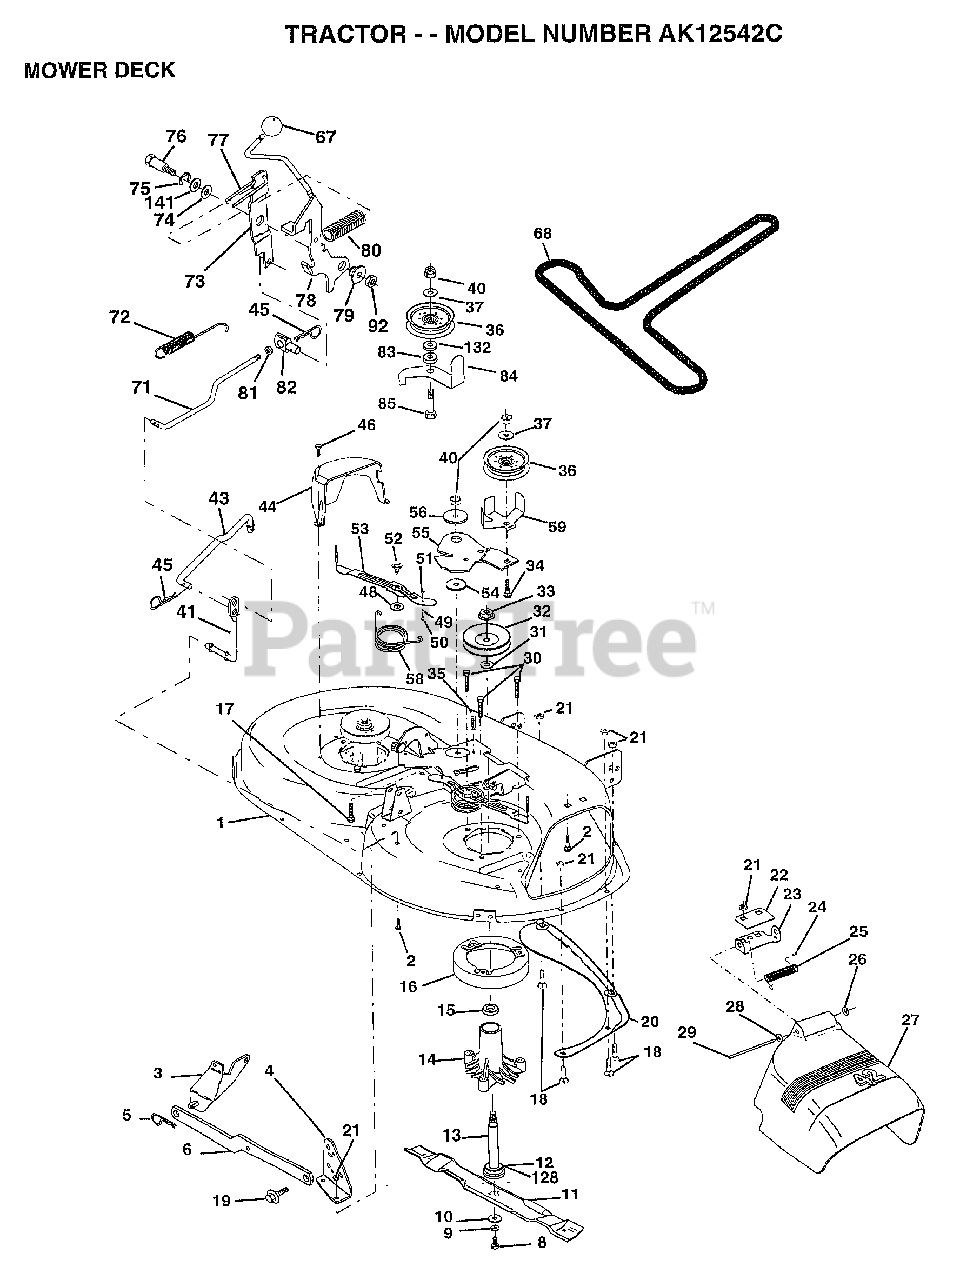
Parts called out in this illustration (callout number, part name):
1	"HOUSING ASSY.42"""
2	BOLT
3	BRKT ASM SWAY BAR
4	BRKT DECK SW BAR
8	BLADE BOLT
10	WASHER.HARD.BLADE
11	"BLADE.42"" HIPERF"
12	BEARING.BALL
14	HSG ASM MANDREL
15	BEARING
16	STRIPPER RND MWR
17	BOLT RDHD 3/8-16
18	BOLT
19	BOLT SHD 5/16-18
20	BAFFLE VORTEX 42
22	STIFFENER BRKT
23	DEFLECTOR BRKT
24	CAP-SLEEVE LT
25	SPRING TORSION
26	NUT PUSH M
27	DEFLECTOR.SHIELD
28	WASHER
29	HINGE ROD
30	"SCREW-THD ROLL,WA"
31	WASHER
32	PULLEY.MANDREL.42
34	BOLT
35	XMAS TREE FASTNER
36	FLAT IDLER PULLEY
37	WASHER
41	PIVOT ROD
43	ROD CLUTCH W/NIBS
44	GUARD MAND LH BLK
45	RETAINER M
46	SCREW.1/4-20X5/8
48	HARD SMALL WASHER
49	ROLLER ASM-CAM
50	SHOULDER BOLT
51	LOCKNUT
52	BOLT.SHLD.5/16-18
53	BRAKE PAD ARM ASM
54	HARDENED WASHER
55	ARM-IDLER
56	SPACER RETAINER
58	SPRING TORSN BRAK
59	GUARD IDLER TUV
67	KNOB.RD.7/16-14
68	BELT.V.T-PATH
71	ROD CLUTCH 38/42
72	RETURN SPRING
73	CLUTCH ARM SECOND
74	WASHER
75	RING
76	SHOULDER BOLT
77	SPRING KEEPER
78	LEVER.ASM.CLUTCH
79	BUSHING
80	SPRING.CLUTCH.MWR
81	NUT
82	TRUNION ADJ
83	WASHER
84	"KEEPER-BELT,FIXED"
85	BOLT
92	NUT
128	WASHER.FELT.
132	WASHER GT
141	WASHER .T
